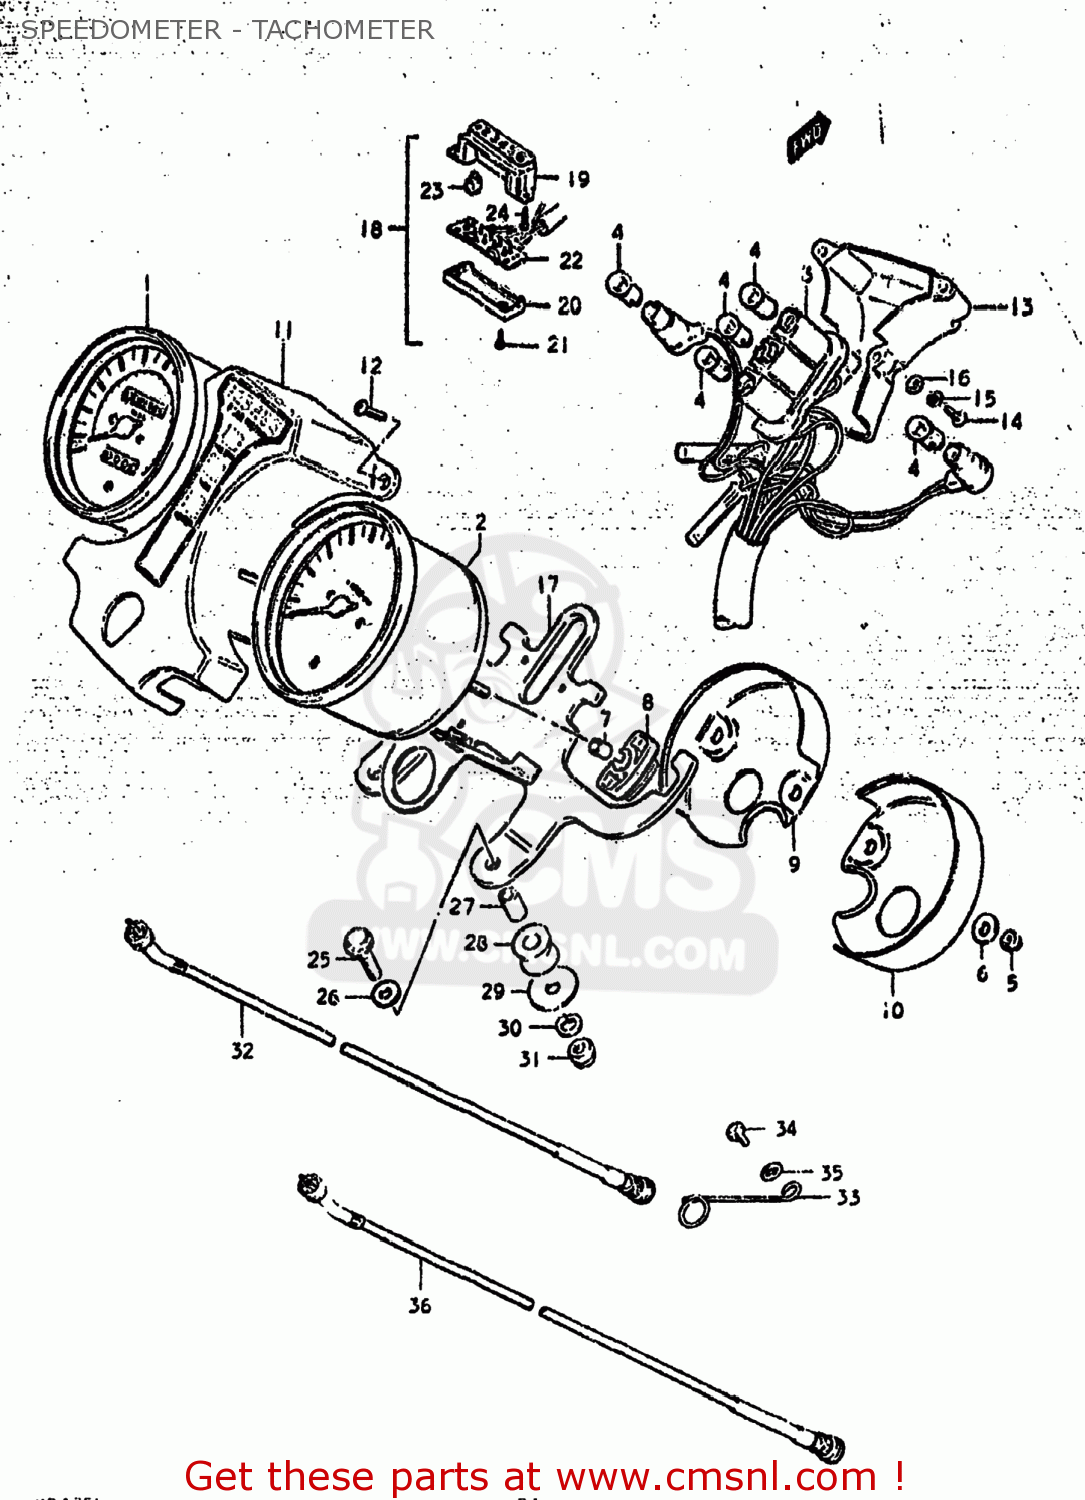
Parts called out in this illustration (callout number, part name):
1	SPEEDOMETER ASSEMBLY
2	TACHOMETER
3	SOCKET,METER
4	BULB(12V3.4W,STANLEY,A72A)
5	NUT
6	WASHER (5.5X16X1.2)
7	SPACER
8	CUSHION,METER
9	UNDER COVER,SPEEDOMETER
10	UNDER COVER,TACHOMETER
11	CASE,PILOT BULB
12	SCREW
13	COVER,PILOT BULB CASE
14	SCREW(4X16)
15	WASHER,PILOT UNDER CASE
16	WASHER
17	BRACKET,METER
18	INDICATOR ASSEMBLY,GEAR POSITION
19	CASE,GEAR INDICATOR
20	COVER,LWR
21	SCREW,GEAR INDICATOR
22	SOCKET,GEAR INDICATOR
23	BULB(14V1.12W)
24	SCREW
25	BOLT
26	WASHER 6MM
27	SPACER (6.1X8X15.5)
28	CUSHION
29	WASHER
30	LOCK WASHER
31	NUT
32	CABLE ASSEMBLY,SPEEDOMETER
33	GUIDE,SPEEDOMETER CABLE
34	BOLT, UPPER
35	WASHER 6MM
36	CABLE ASSEMBLY,TACHOMETER
